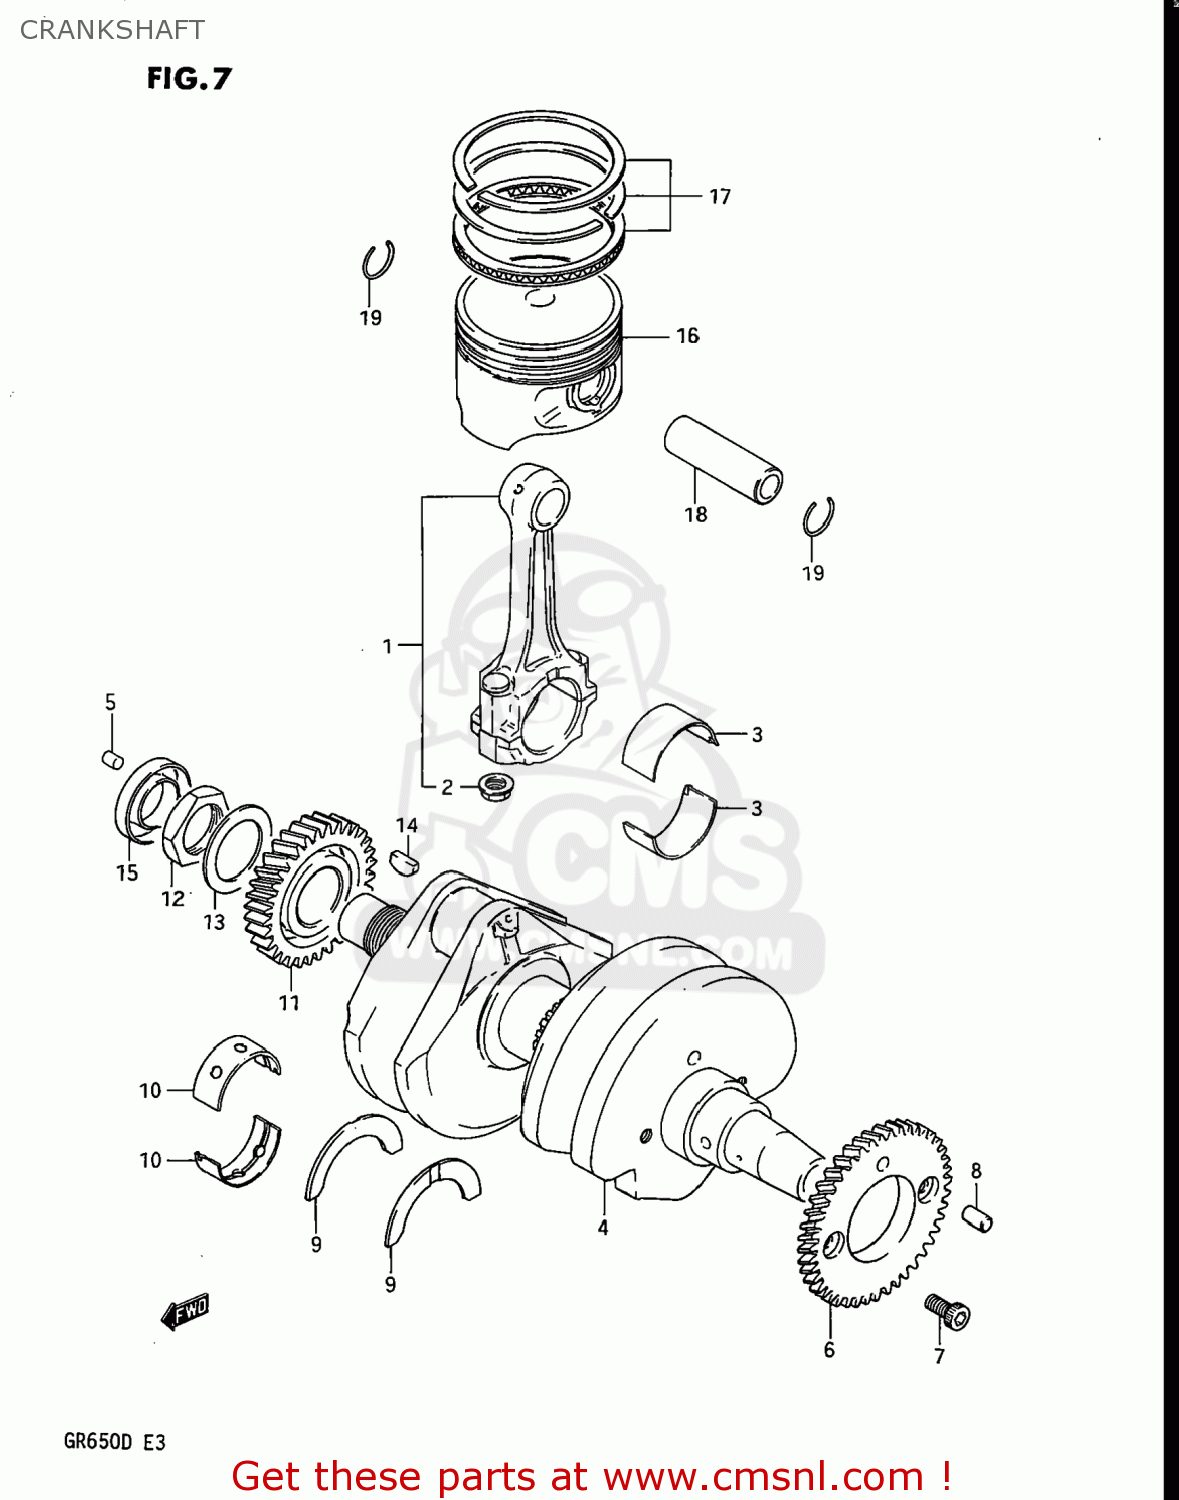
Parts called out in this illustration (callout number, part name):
1	CONNECTING ROD ASSEMBLY
2	NUT
3	METAL CRANK PIN (BROWN)
4	CRANKSHAFT
5	PIN
6	GEAR,CRANK BALANCER DRIVE
7	BOLT
8	PIN
9	PLATE,CRANK THRUST
10	METAL,CRANKSHAFT (GREEN)
11	GEAR,PRIMARY DRIVE
12	NUT
13	WASHER
14	KEY
15	SEAL,OIL(22X40X8)
16	PISTON (77.00MM)
17	RING SET,PISTON
18	PIN,PISTON
19	CIRCLIP
